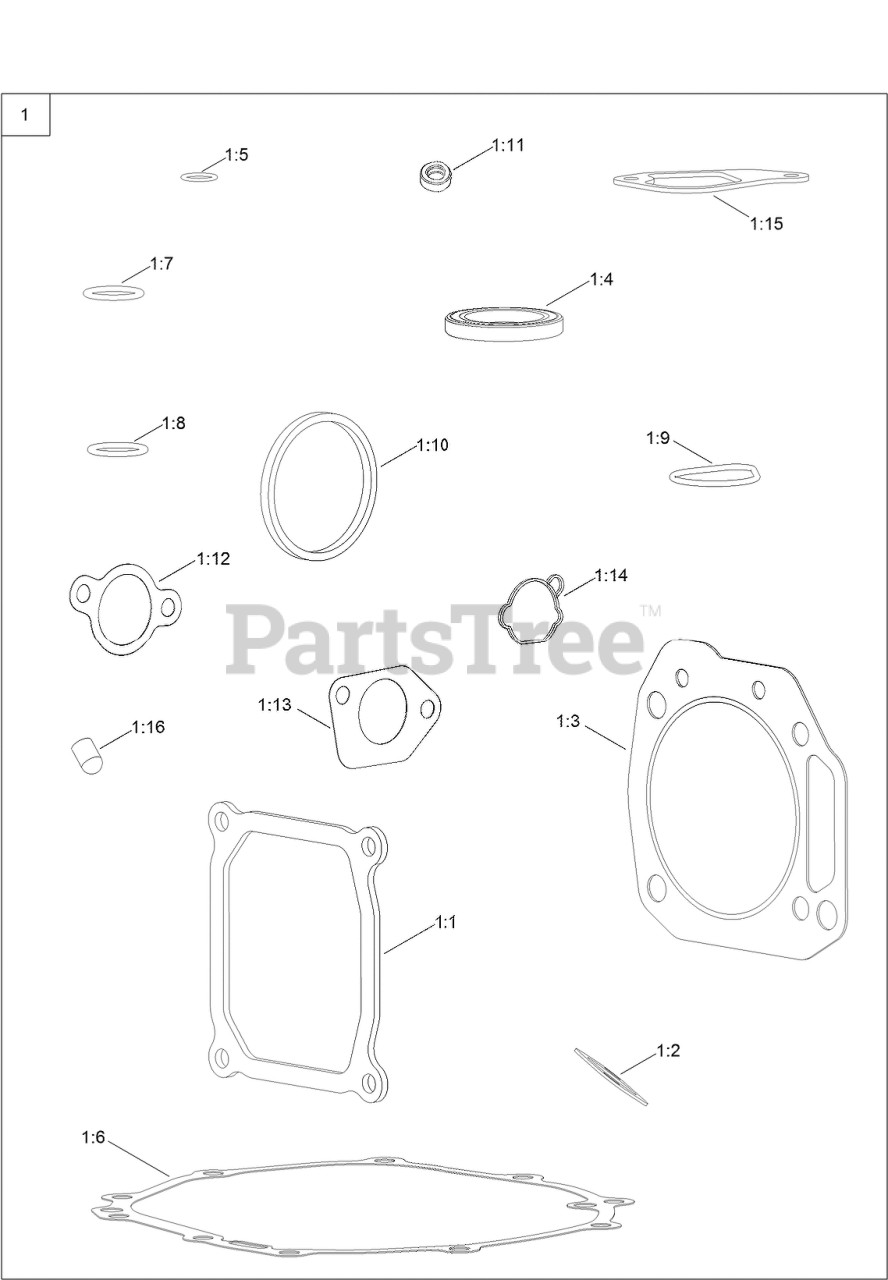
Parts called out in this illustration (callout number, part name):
1	GASKET AND SEAL KIT
1:1	GASKET-COVER, VALVE
1:2	GASKET-EXHAUST
1:3	GASKET-CYCLINDER
1:4	SEAL-OIL
1:5	O-RING
1:6	GASKET-CRANKCASE
1:7	O-RING
1:8	O-RING
1:9	SEAL-PUMP, OIL
1:10	SEAL-ADAPTOR, OIL
1:11	SEAL-OIL
1:12	GASKET-CARBURETOR
1:13	GASKET-CARBURETOR
1:14	GASKET-CARBURETOR
1:15	GASKET-BREATHER
1:16	CAP-SEAL
